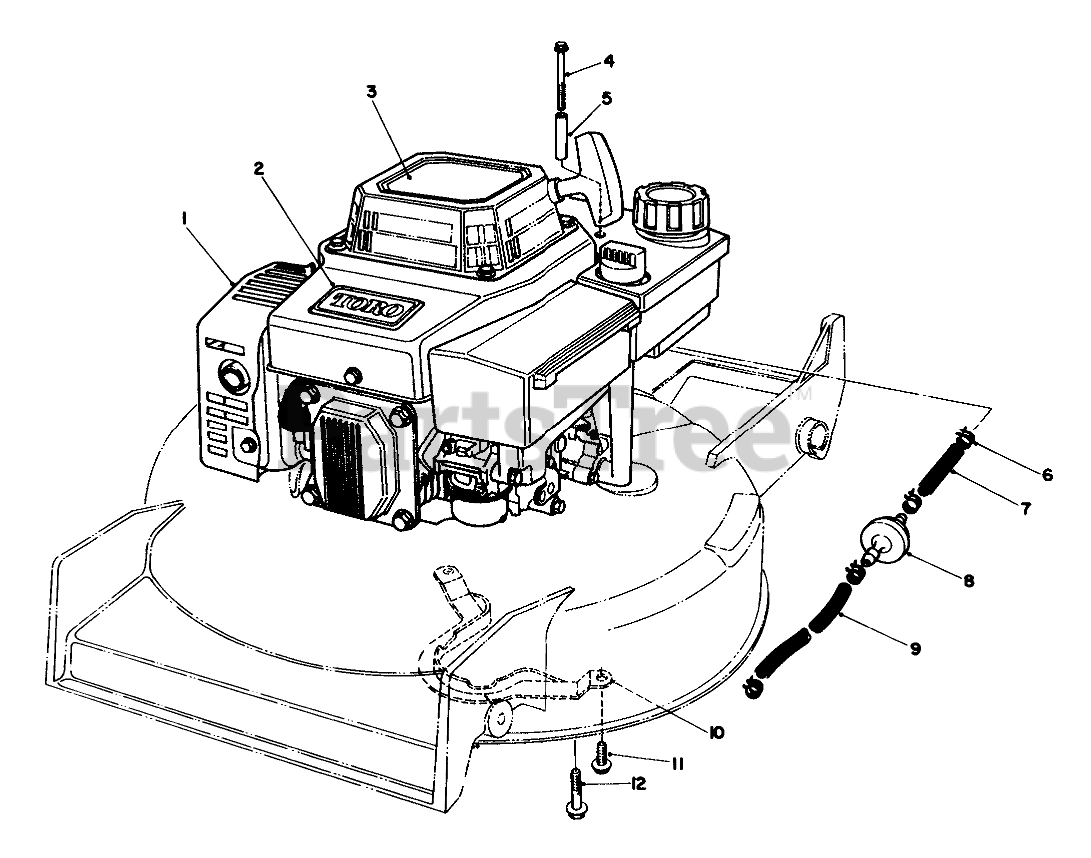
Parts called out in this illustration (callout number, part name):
1	Engine
2	TORO LOGO PLT
3	DECAL - RECOIL GTS
4	THRD FORMING SCREW
5	TUBULAR SPACER
6	CLAMP-FUEL LINE
7	LINE-GAS
8	FILTER-FUEL
9	HOSE-FUEL
10	BELT GUIDE
10	BBC BELT GUIDE
11	Screw
12	SCREW-HWHTF
